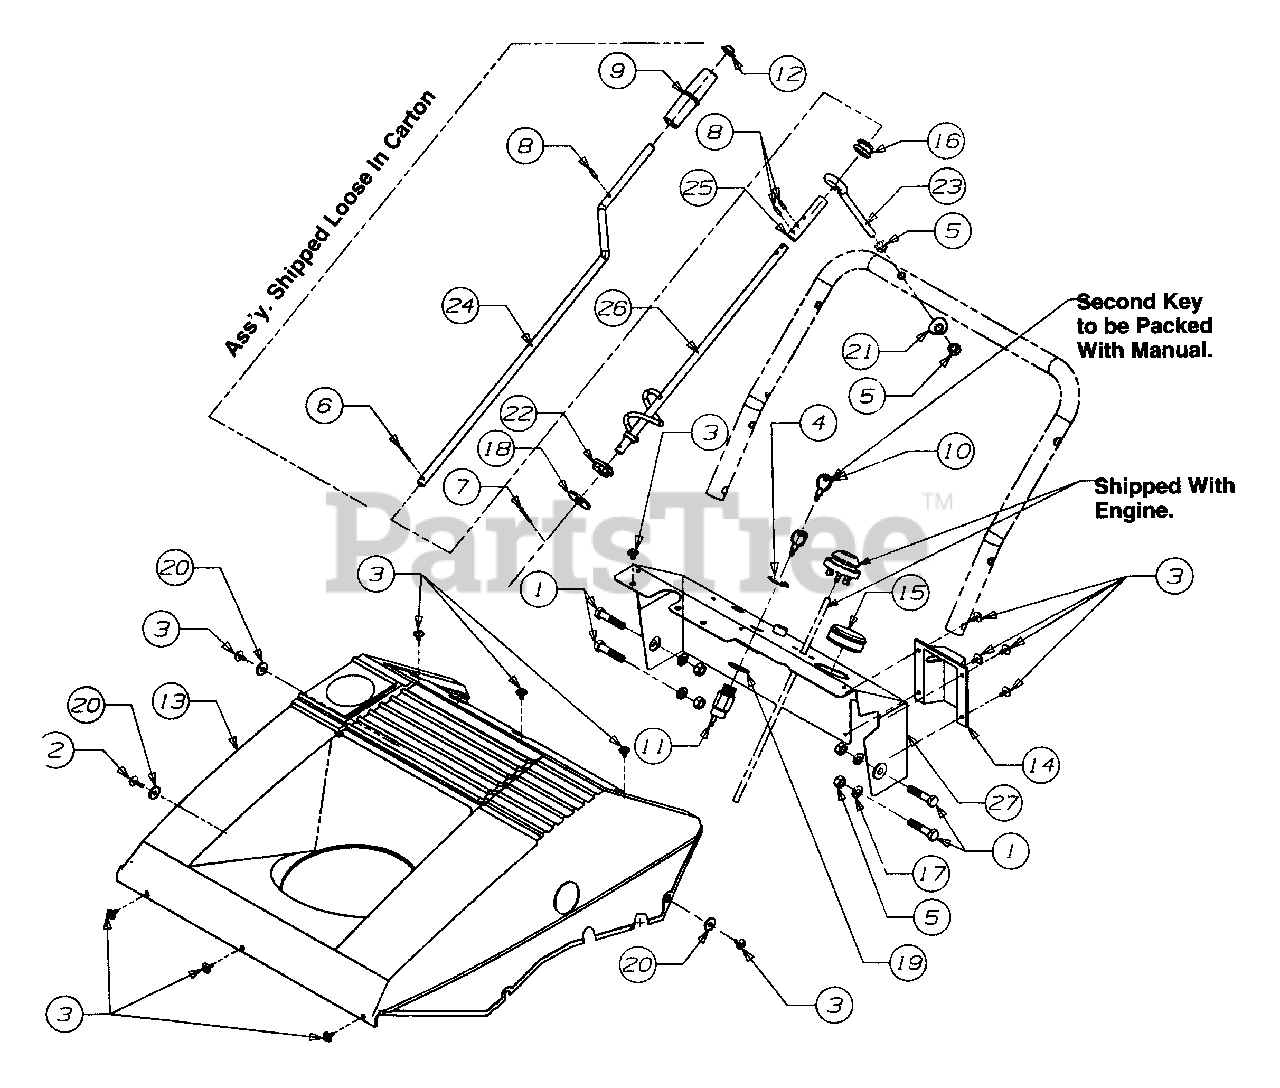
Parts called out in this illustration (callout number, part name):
1	Screw-Hex
2	Screw Hex Wash Tap
3	Screw Hex B-Tap
4	Nut-Hex
5	Nut-Hex
6	Cotter Pin
7	Cotter Pin
8	Pin-Roll
9	Knob-Chute Crank
10	Key-Ignition
11	Switch-Key
12	Nut Push
13	Shroud-21"
14	Choke Cover
15	Plug Plastic
16	Grommet
17	Washer Lock
18	Washer Flat
19	Washer-Internal Lock
20	Washer Flat
21	Washer Saddle
22	Bushing Hex
23	Eyebolt
25	Spacer
26	Crank Ass'y. Chute Lower
